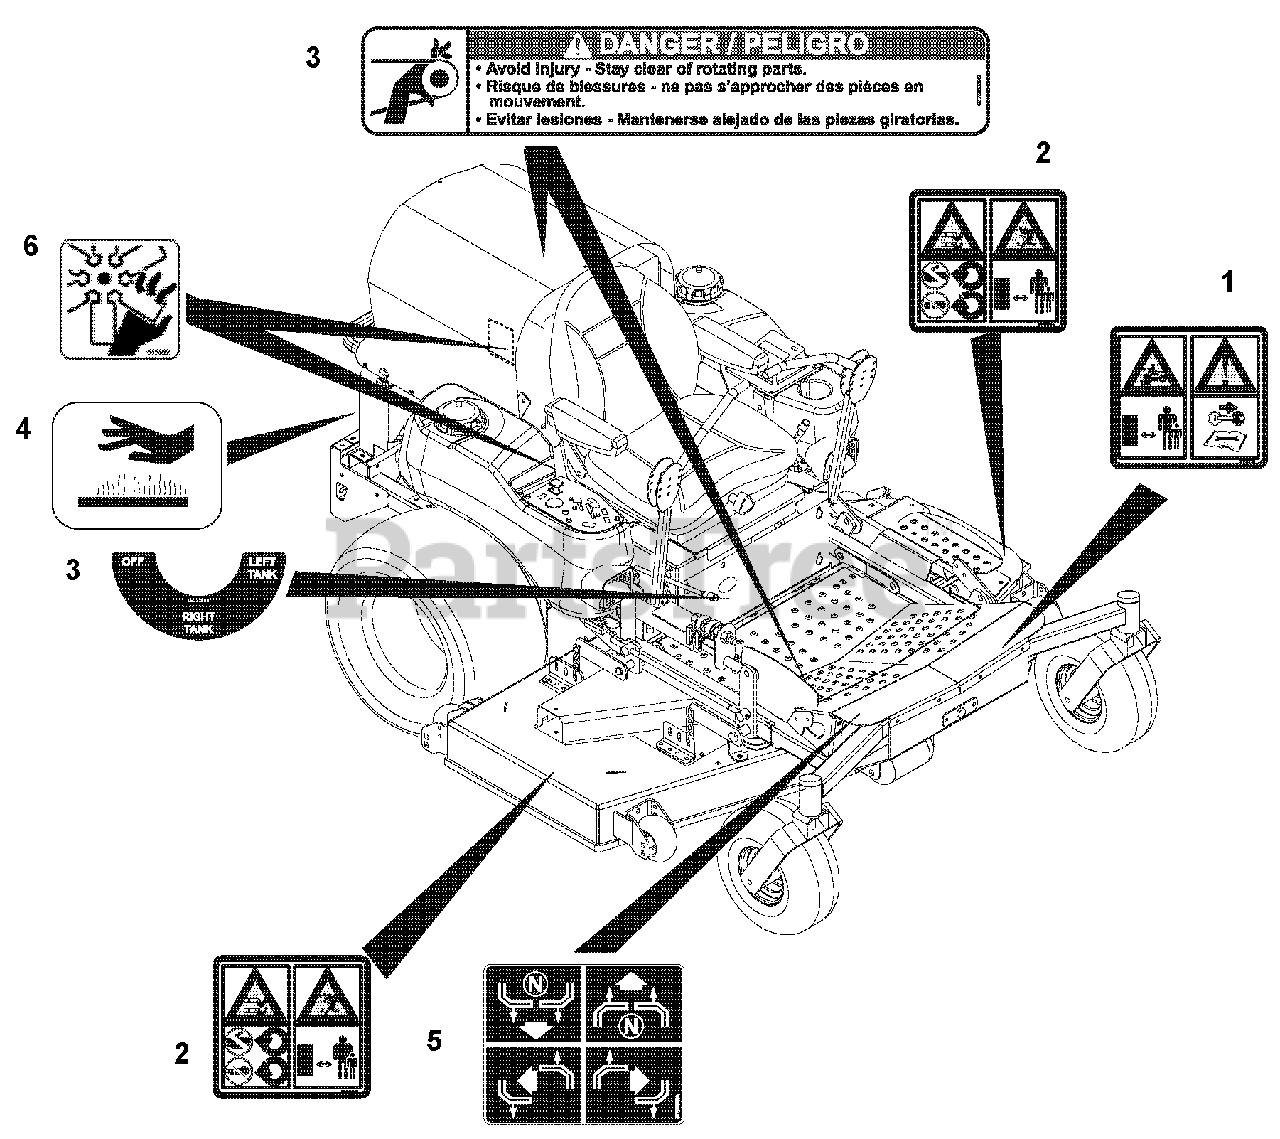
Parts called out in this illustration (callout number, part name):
1	DECAL, CE CAUTION
2	DECAL, CE DECK
3	SET, DECAL-COMMON DANGER/FUEL
4	DECAL, HOT SURFACE
5	DECAL, INSTRUCTIONAL-STEERING
6	DECAL, DANGER FAN
